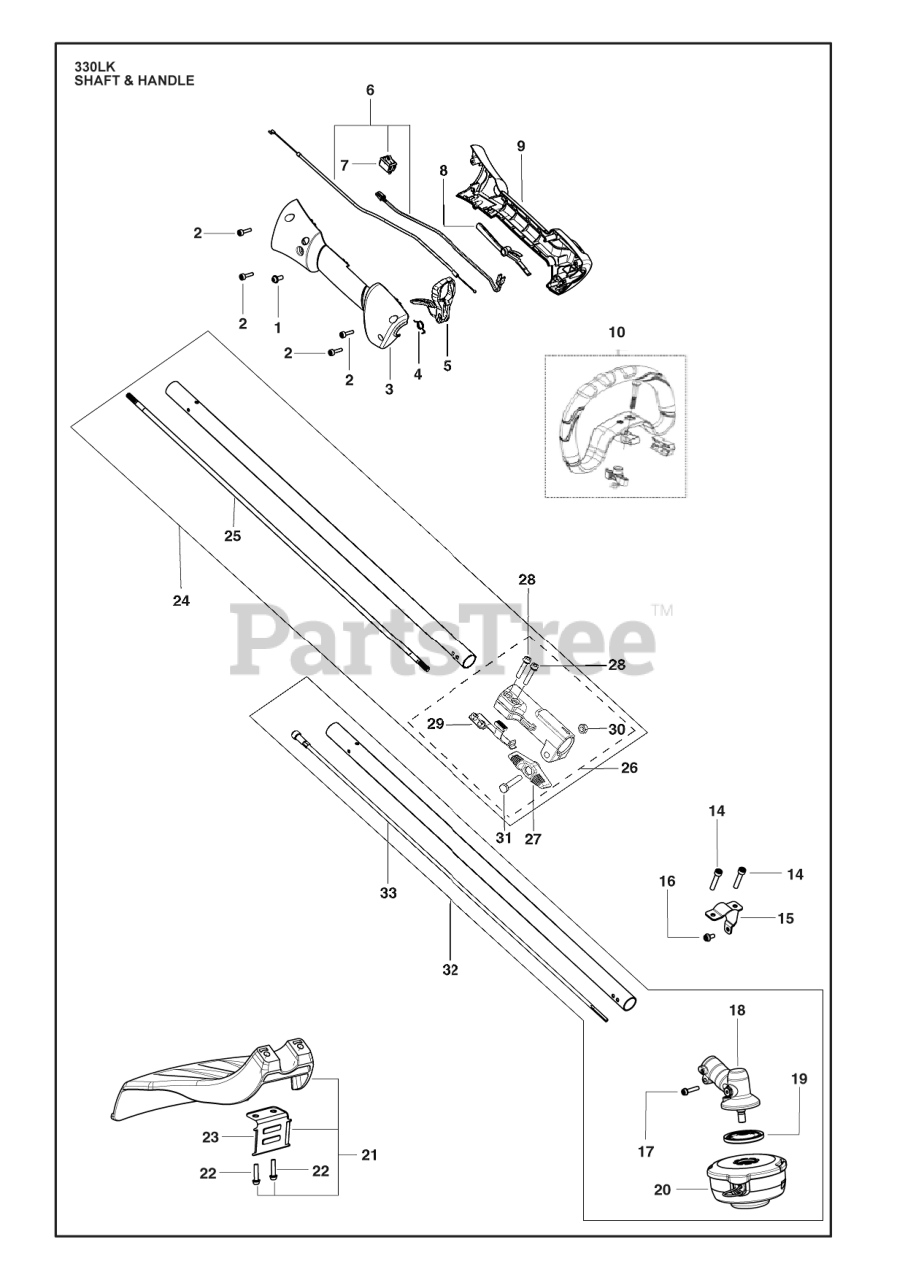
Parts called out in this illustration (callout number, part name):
1	SCREW
2	SCREW
3	HOUSING THROTTLE
4	SPRING TRIGGER
5	TRIGGER THROTTLE HVA ORANGE
6	ASSY CABLE / WIRE HARNESS
7	SWITCH
8	THROTTLE LOCKOUT HVA ORANGE
9	HOUSING THROTTLE
10	HANDLES
14	BOLT, TORX
15	BRACKET
16	BOLT
17	SCREW
18	BEVEL GEAR
19	DRIVER ASSY
20	TRIMMER HEADS
21	GUARD ASSY KIT
22	SCREW
23	BLADE
24	SERVICE KIT 330LK TRIMMER UPP
25	DRIVE SHAFT ASSY
26	CLAMPING SLEEVE ASSY
27	KNOB CLAMPING SLEEVE
28	SCREW
29	LOCKING PLATE ASSY CLAMPING SL
30	NUT
31	BOLT FLANGE
32	SERVICE KIT 330LK TRIMMER LOW
33	DRIVE SHAFT
